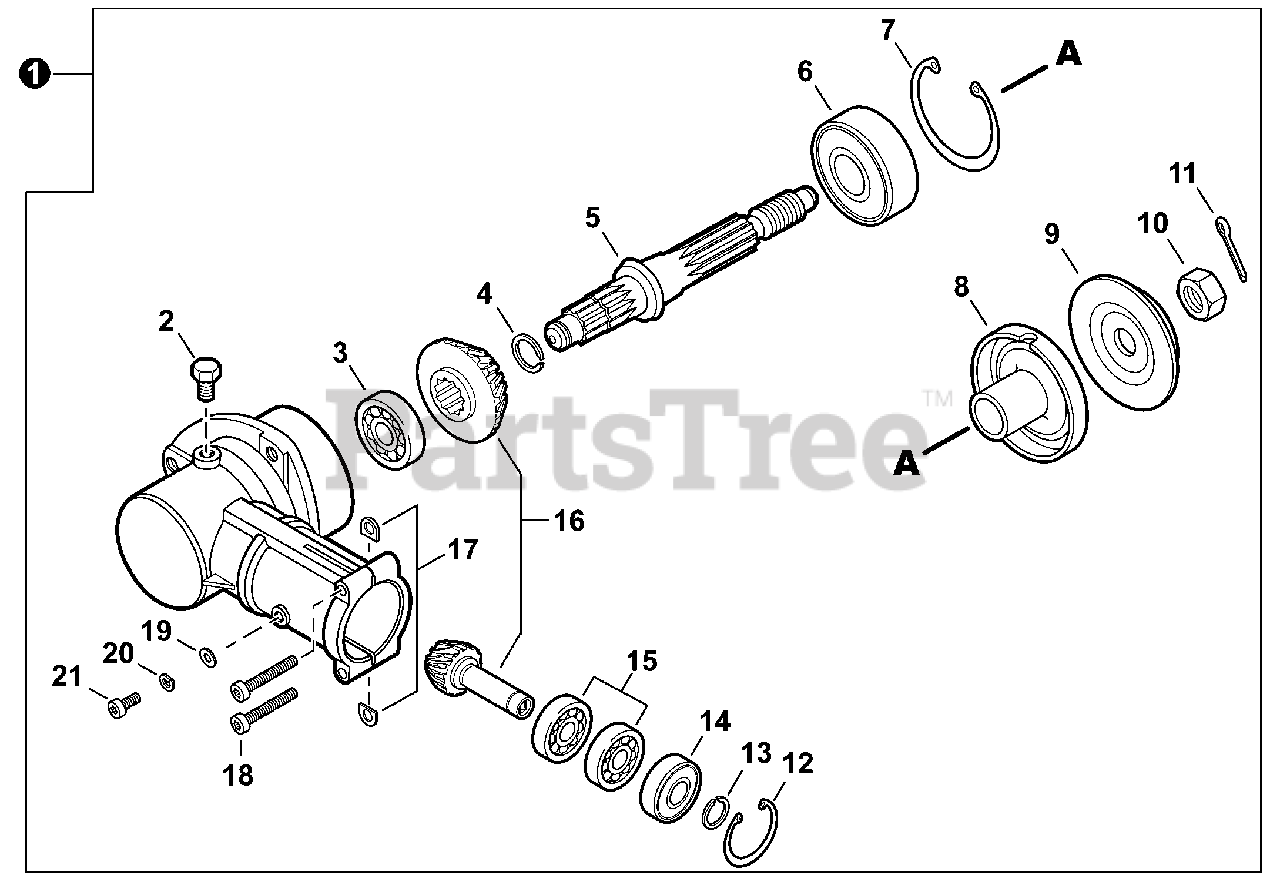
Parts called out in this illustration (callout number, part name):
1	GEAR CASE ASSY
2	BOLT M8×1.25
3	BEARING, BALL 629
4	RING, SNAP 12
5	SHAFT, GEAR
6	BEARING, BALL 6302
7	RING, SNAP 42
8	PLATE, ADAPTOR - UPPER
9	PLATE, ADAPTOR - LOWER
10	NUT 10×1.25 LH
11	PIN, COTTER 2×22
12	RING, SNAP 22
13	RING, SNAP 10
14	BEARING, BALL 6900-Z
15	BEARING, BALL 6900
16	GEAR SET
17	D-WASHER
18	BOLT, TORX 5×25
19	WASHER, FLAT 5.5×10×0.8
20	WASHER, SPRING 5
21	BOLT, TORX 5×10
